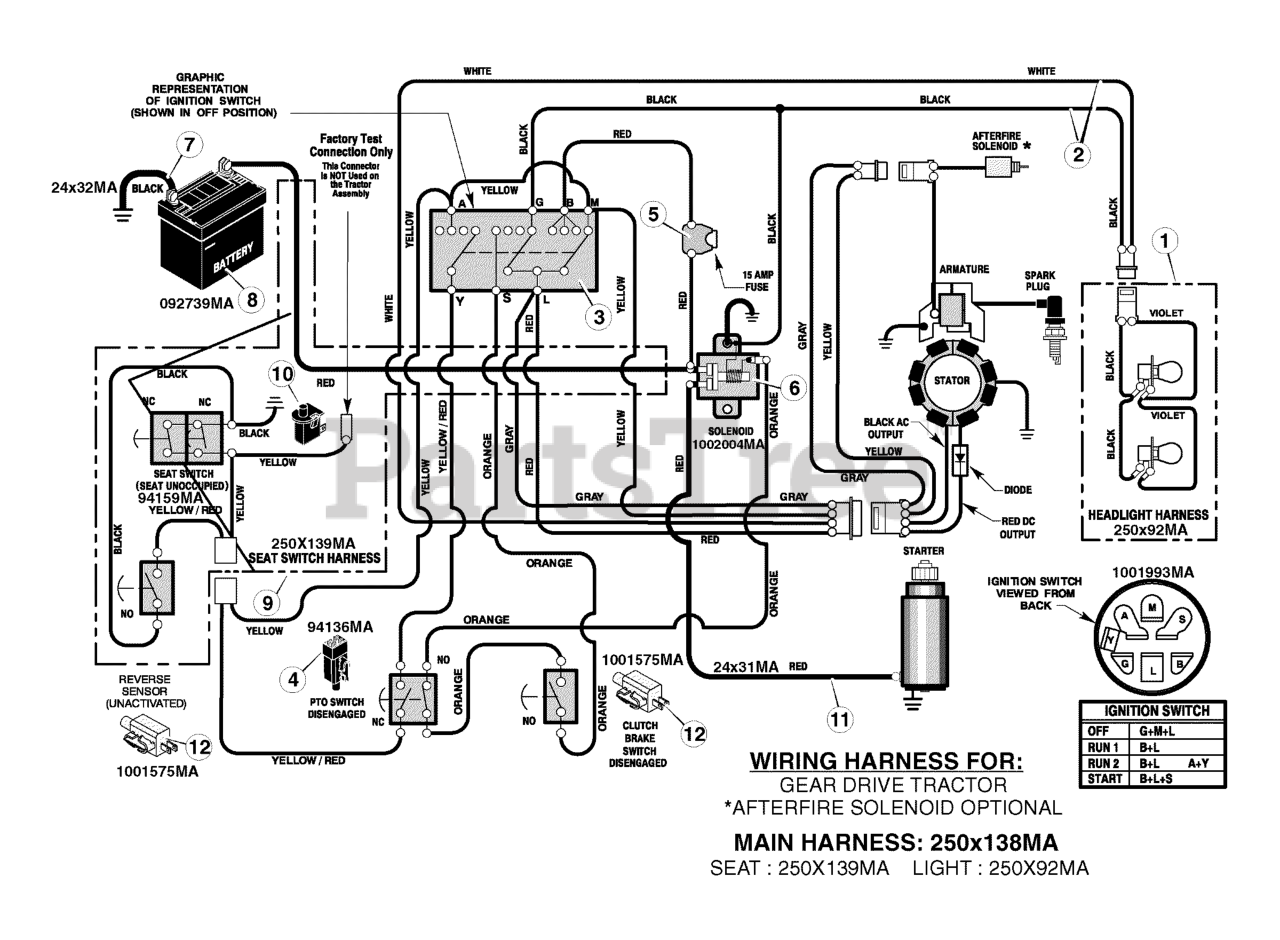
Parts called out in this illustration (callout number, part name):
1	Harness, Light Wire
2	Harness, Chassis Wire
3	Switch, Ignition
4	Switch, Limit
6	Solenoid
7	Cable, Battery Ground
8	Battery
9	Harness, Seat Switch Wire
10	Switch, Seat Sensor
12	Switch, Limit
